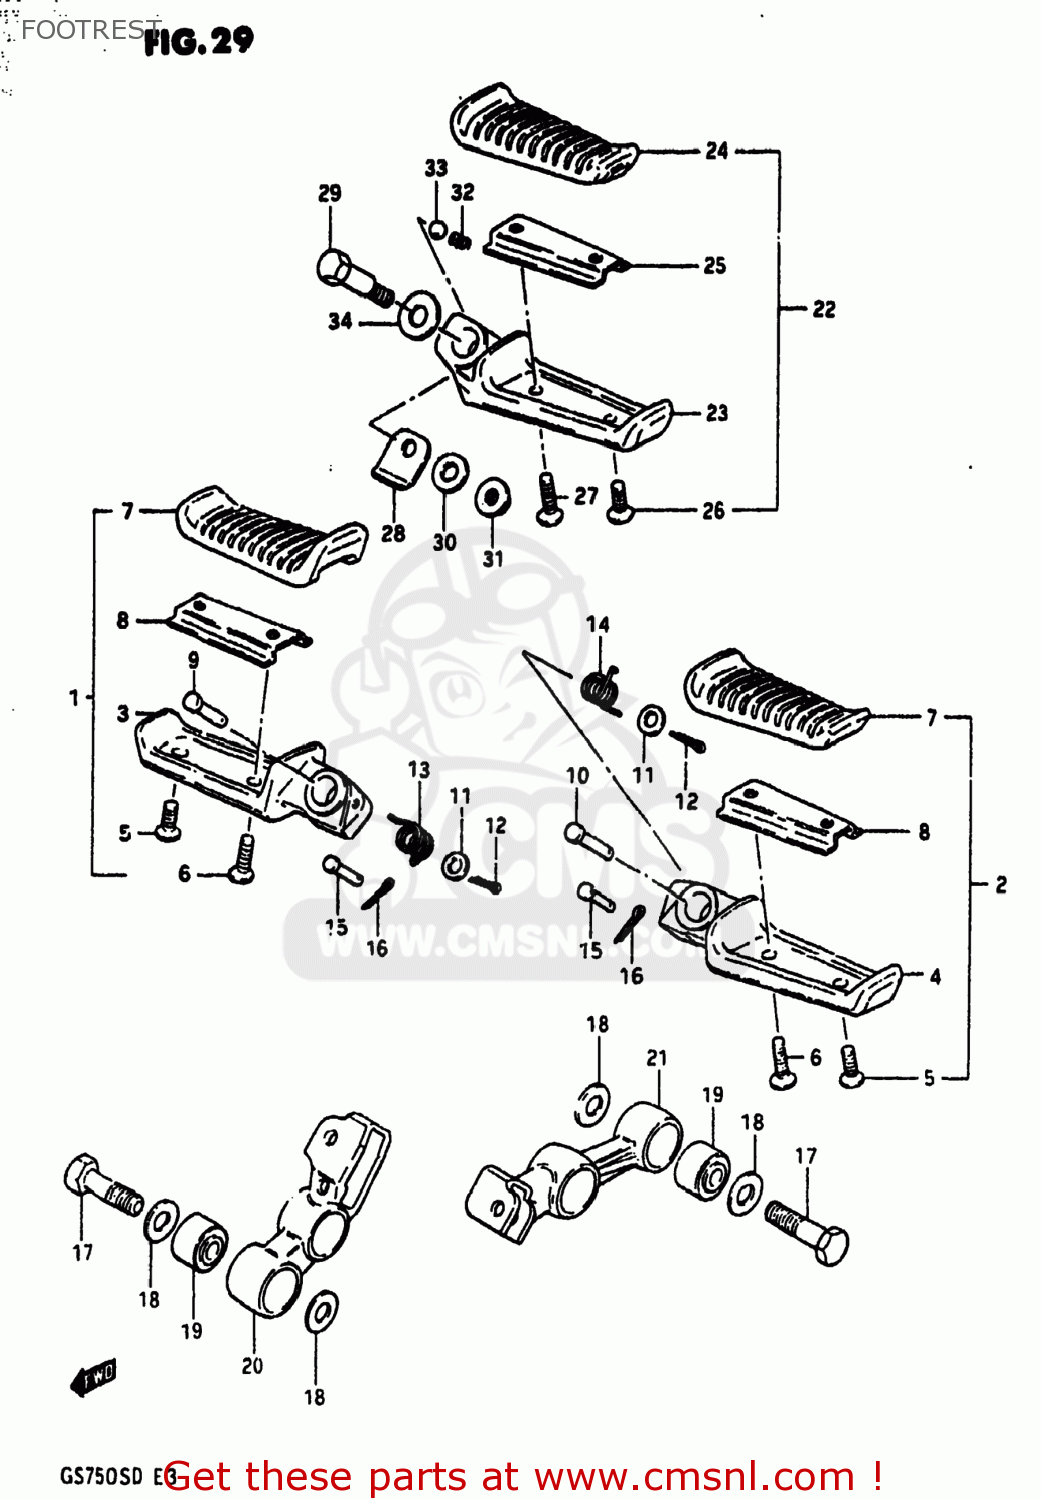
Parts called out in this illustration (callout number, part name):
1	FOOTREST ASSEMBLY,FRONT,RIGHT
2	FOOTREST ASSEMBLY,FRONT,LEFT
3	BAR,FRONT FOOTREST
4	BAR,FRONT FOOTREST,LEFT
5	SCREW
6	SCREW
7	RUBBER,FR FOOTREST
8	PLATE,FR FOOTREST RUBBER
9	PIN
10	PIN
11	WASHER
12	PIN 20X20
13	SPRING
14	SPRING
15	PIN
16	PIN 20X20
17	BOLT
18	WASHER
19	BUSH
20	HOLDER,FR FOOTREST,R
21	HOLDER,FR FOOTREST,L
22	FOOTREST ASSY,PILLION,R
23	BAR,PILLION FOOTREST,LEFT
24	RUBBER,PILLION FOOTREST
25	PLATE,RUBBER STOPPER
26	SCREW 5X12
27	SCREW
28	PLATE,SPRING STOP
29	BOLT(6X45)
30	WASHER
31	NUT
32	SPRING
33	BALL
34	SHIM(8.2X22X0.2)
